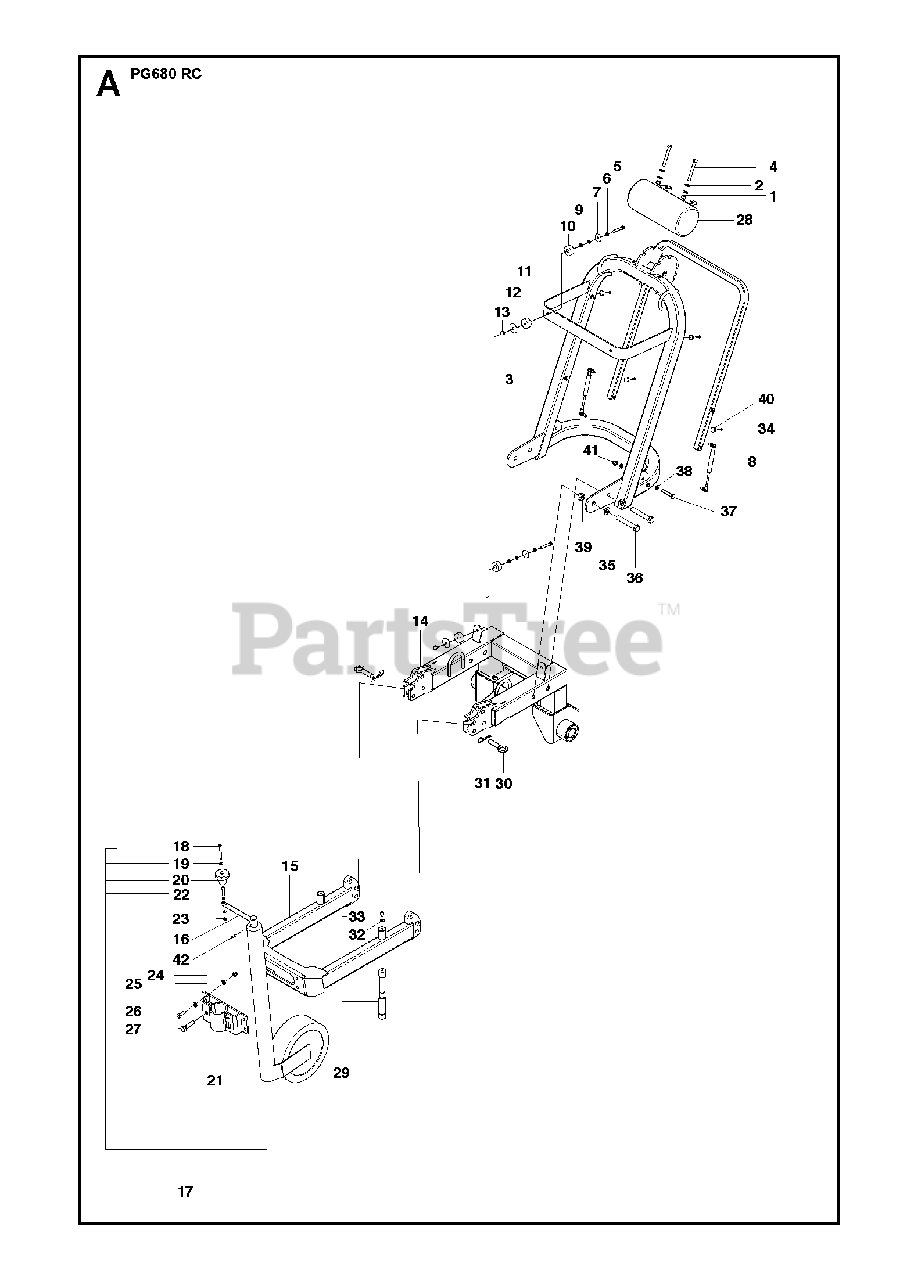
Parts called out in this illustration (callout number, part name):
1	HEXAGON LOCKING NUT
2	WASHER
9	HEXAGON LOCKING NUT
23	HEXAGON LOCKING NUT
24	HEXAGON LOCKING NUT
25	WASHER
31	SPRING COTTER
38	WASHER
41	HEXAGON LOCKING NUT
